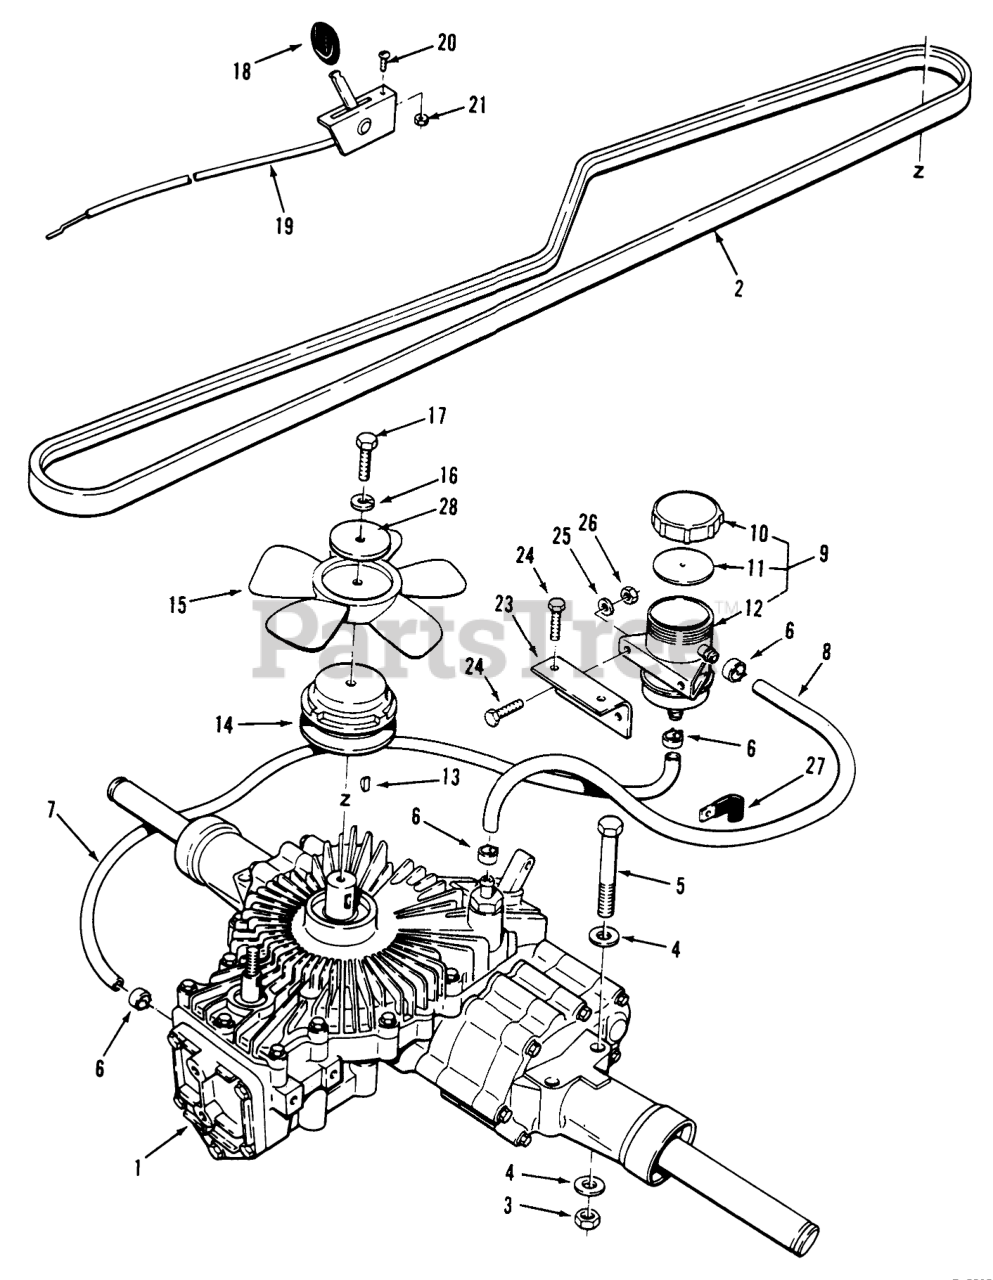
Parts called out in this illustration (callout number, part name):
1	TRANSMISSION 750-019
1	Hydrostatic Transaxle (Eaton Model 750-012)
1	Rebuilt Hydromatic Transaxle
2	BELT V
3	NUT-LOCK, NI
4	WASHER-PLAIN
5	SCREW-HH
6	CLAMP
7	S/A 27" OF 114702
8	S/A 9" OF 114702
9	Reservoir Assembly (Incl. Ref. #10-12)
10	Cover
11	COVER GASKET
12	RESERVOIR
13	HARD HI PRO KEY
14	PULLEY-HYDRO
15	BLADE-FAN
16	Washer
17	Bolt
18	KNOB-THROTTLE
19	CABLE-PUSH VALVE
20	Screw
21	Nut
23	BRKT-RESERVOIR MT R
24	SCREW-HH
25	WASHER-FLAT
26	NUT-LOCK, NI
27	CLIP
28	WASHER
